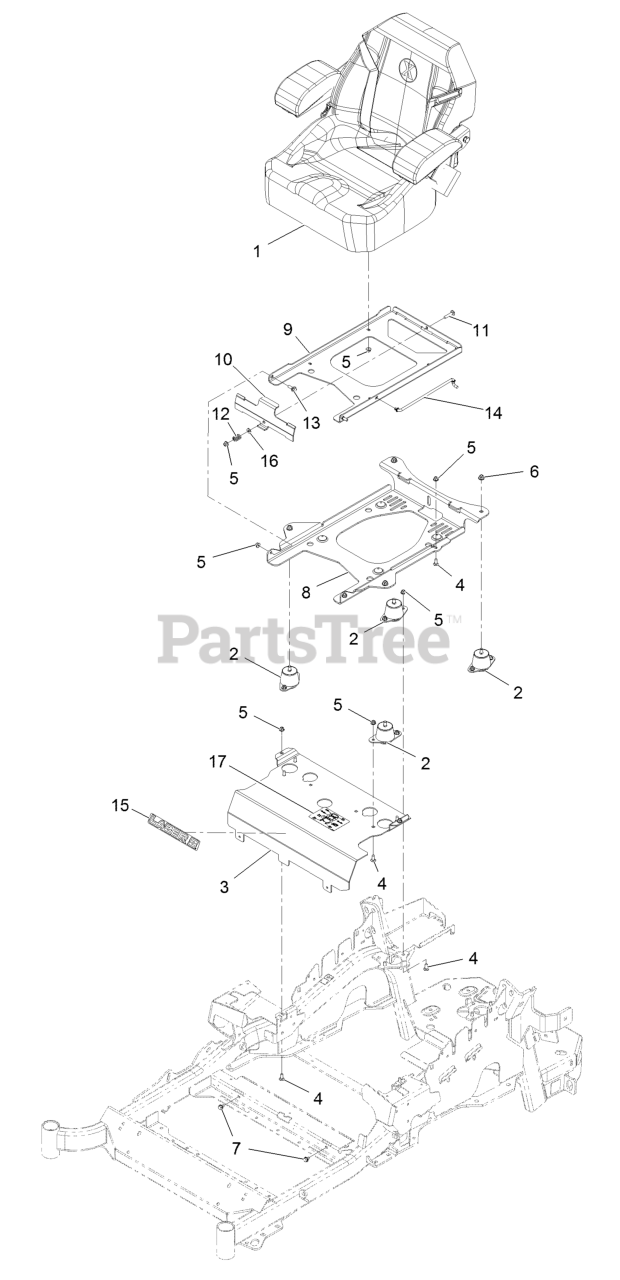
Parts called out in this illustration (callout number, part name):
1	SEAT-EXMARK STANDARD
2	ISOLATOR-SEAT
3	Panel,Seat Mount-Front
4	SCREW-CARR
5	NUT-HF, NI
6	NUT-HF, NI
8	PLATE-TILT, SEAT SUPPORT
9	PLATE-FRAME, SEAT
10	PLATE-LATCH, SEAT
11	BOLT-CARR
12	SPRING-COMPRESSION
13	SCREW-SHOULDER
14	ROD-PROP
15	DECAL, LAZER MODEL
16	WASHER-PLAIN
17	DECAL-SERVICE AID
